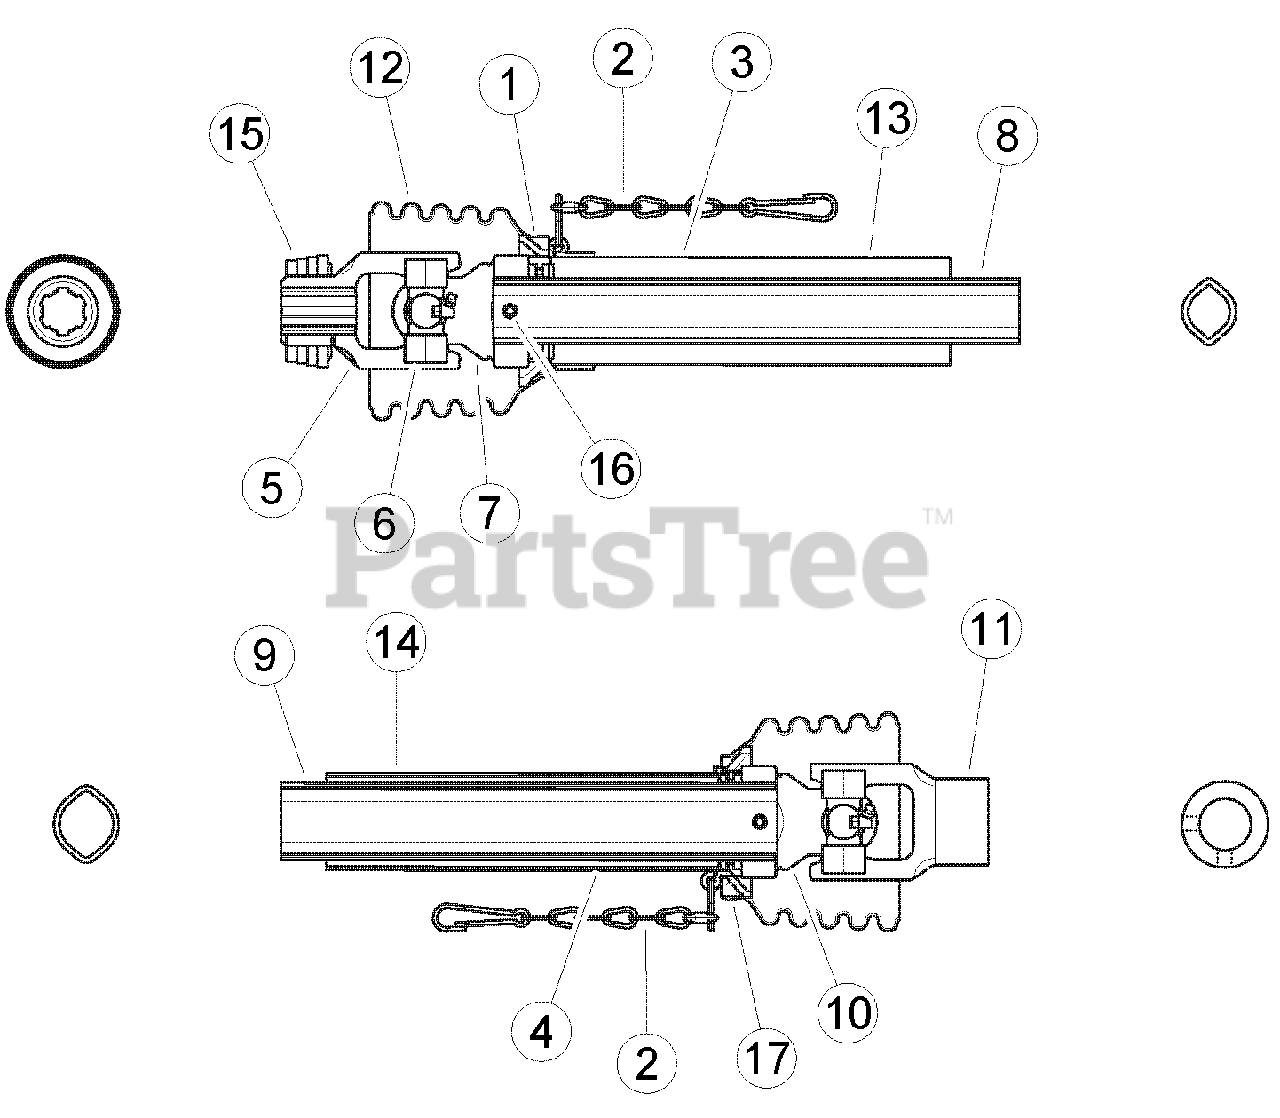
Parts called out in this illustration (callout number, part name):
1	BEARING, RING SC15
2	SAFETY CHAIN
3	DECAL, OUT
4	DECAL, IN
5	YOKE, 3/8 - 6 SPL. ASGE
6	CROSS & BEARING KIT
7	YOKE, INBOARD OV
8	INNER PROFILE OV
9	OUTER PROFILE I
10	YOKE, INBOARD I
12	SHIELD, CONE 4 RIB
13	SHIELD, OUTER TUBE OVL.
14	SHIELD, INNER TUBE RND
15	KIT, RETAINING RING / TRACTOR SIDE
16	PIN, SPRING 10 X 65
